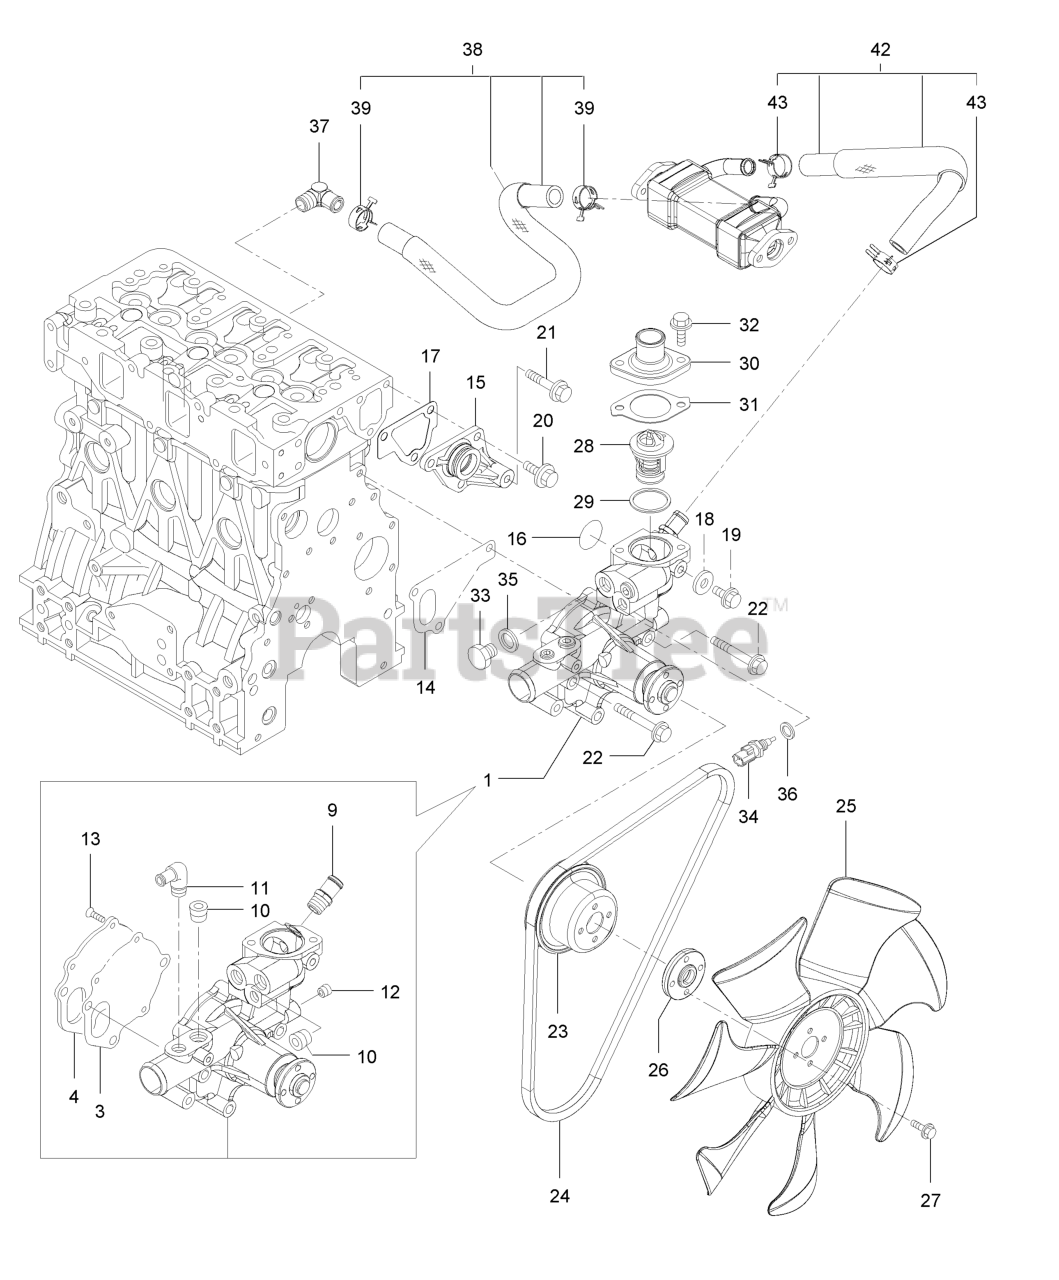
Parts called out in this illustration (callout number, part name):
1	Water Pump ASM
20	Bolt
23	V-Pulley
28	Thermostat
34	Sensor-Thermostat, CW
36	Washer-Seal
38	E G R-C Pipe ASM
39	Clip-Hose
42	CW Pipe ASM
43	Clip-Hose
